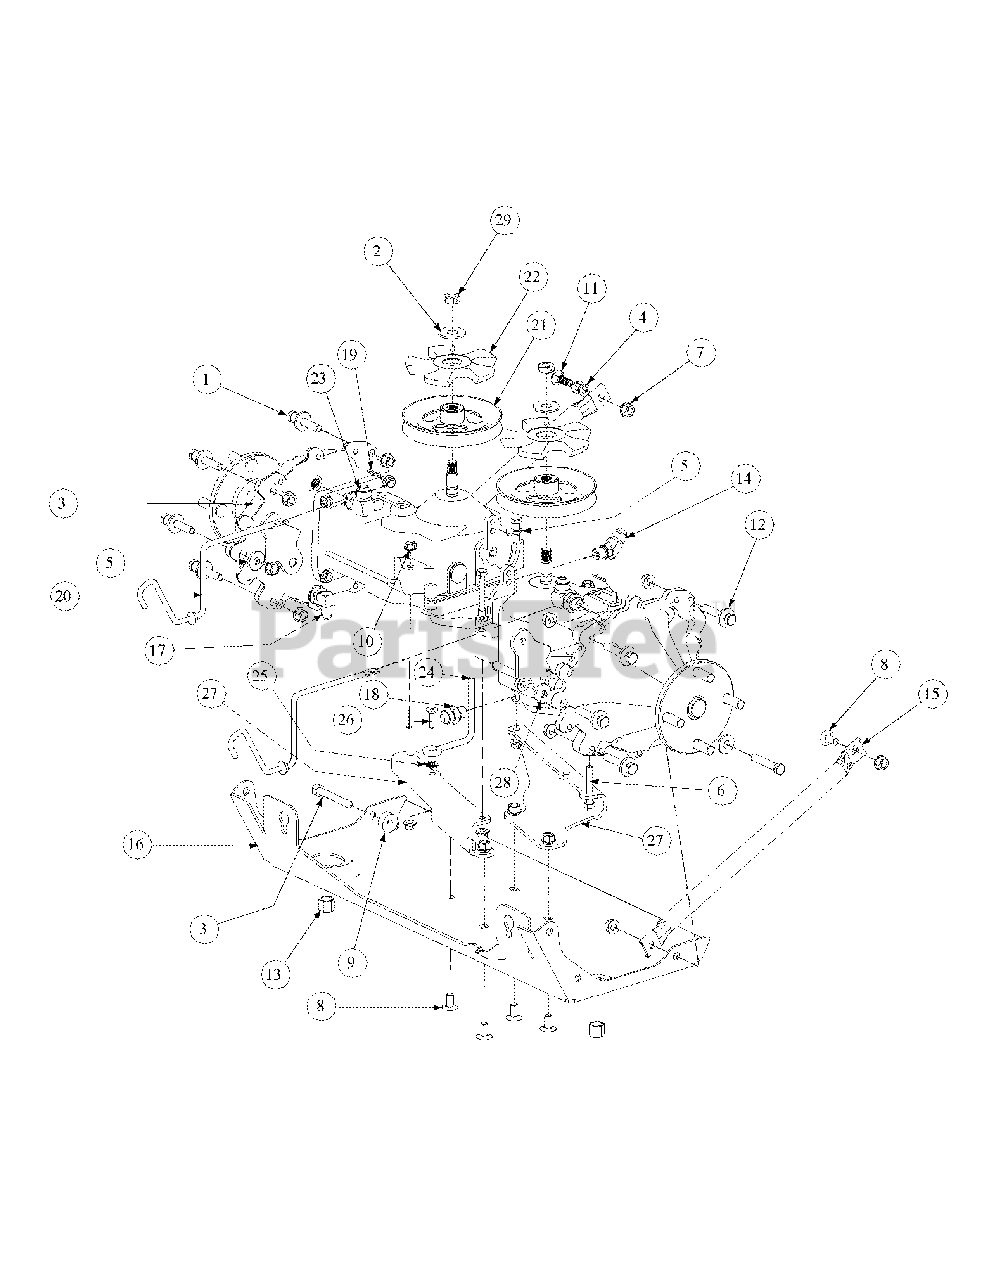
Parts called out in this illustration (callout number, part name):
1	Hex Cap Screw, 3/8-16 x 2
2	Flat Washer, 1/2
3	Hex Cap Screw, 3/8-16 x 2.5
4	Lock Washer, 3/8
5	Flat Washer, 5/16
6	Hex Cap Screw, 5/16-18 x 2
7	Flange Lock Hex Nut, 3/8-16
8	Carriage Bolt, 3/8-16 x .75 Long
9	Spacer, .406 ID x 1.00 OD x .38
10	Hex Flange Lock Nut, 5/16-18
11	Carriage Bolt, 3/8-16 x 1
12	Washer, .406 ID x 1.0 OD x .105
13	Nut Cap, 3/8
14	Elbow Fitting, 3/8 - 1/2 x 45°.
16	Skid Plate
17	Elbow Fitting, 3/8 x 3/8
18	Fitting, 1/2 x 3x8
19	Cotter Pin, .072 x 1.12 Long
20	Pump Release Rod
21	Slotted Hydro Pulley
22	Pulley Hydro Fan
23	Elbow Fitting, O-Ring 3/8, 1/2 Flare
24	Belt Guide
25	Washer
26	Screw, 5/16-18 x 1.00
27	Support Mount Bracket
28	Flat Washer, .385 x 1.0 OD x .13
29	Nut, 1/2-20, Center Lock
